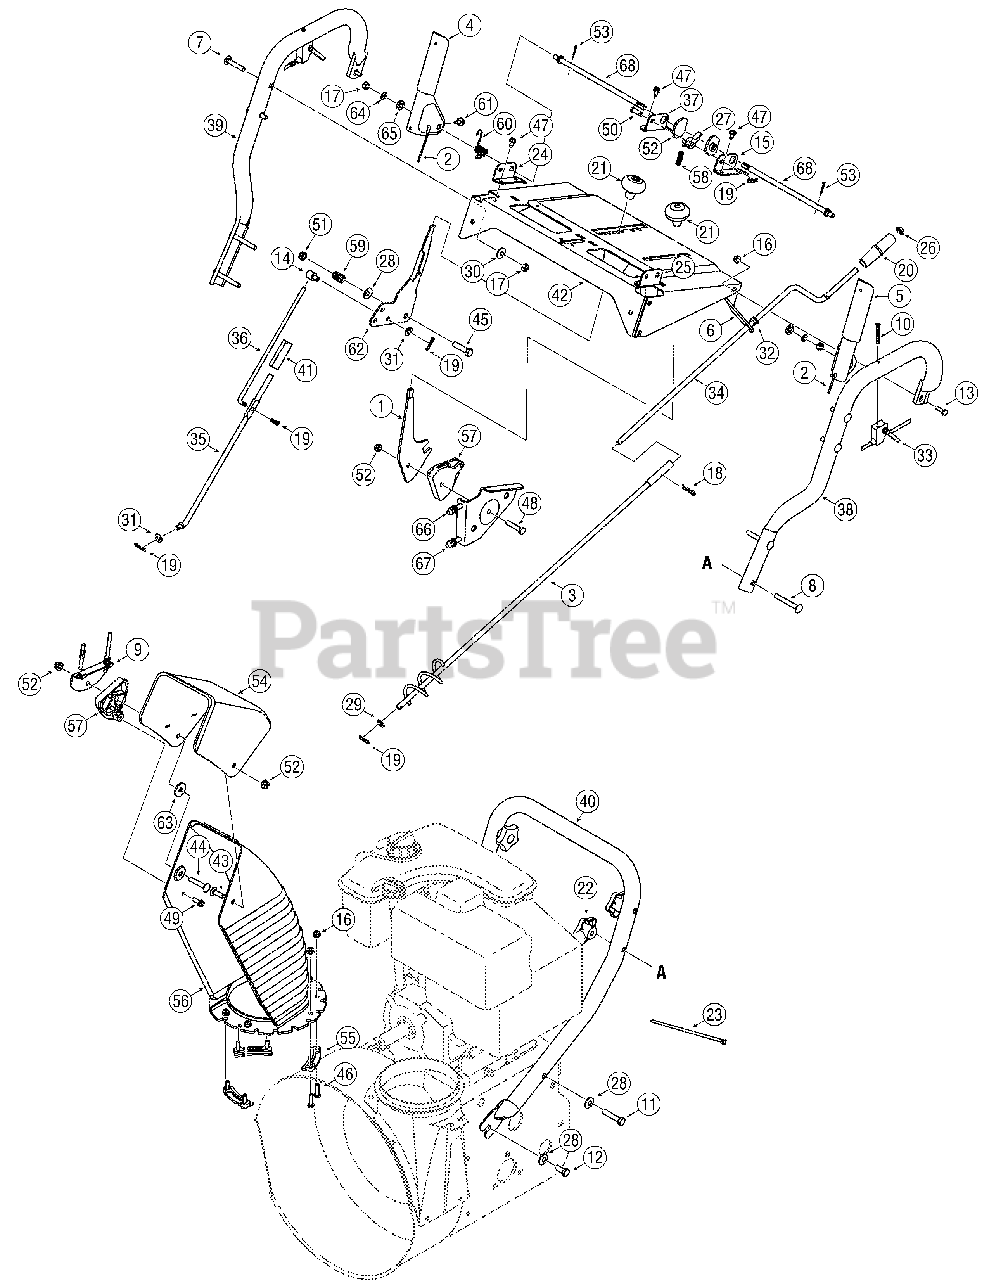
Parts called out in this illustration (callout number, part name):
1	Chute Tilt Handle
2	Cable Ass’y (Auger/Drive)
3	Lower Chute Crank Assembly
4	Engage Handle RH Black
5	EngagementHandle LHBlack
6	Upper Chute Crank Support
7	Carriage Bolt 5/16-18 x 1.75" Lg.
8	Carriage Bolt 5/16-18 X 2.50
10	Screw, #10-24 x 1.75
11	Hex Screw 3/8-16 x 1.75
12	Hex Screw 3/8-16 x .88
13	Hex Cap Bolt 1/4-20 x .75" Lg.
14	AdjustmentFerrule
15	LH Handle Support Brkt. 5/8"
16	Hex L-Flanged Nut 1/4-20 Gr. F Nylon
17	Hex Nut 5/16-18 hd. (Gr. 5)
18	Internal Cotter Pin
19	Int. Cotter Pin .072 x 1.13" Lg.
20	Knob 1.0 x 3.2
21	Shift Knob
22	Star Knob
23	Cable Tie
24	RH Handle Support Brkt. 3/8"
26	Push Nut 3/8" Rod
27	Cam Lock Pawl
28	Cupped Washer .375 ID x .870 OD x .063
29	Flat Washer .406" I.D. x .75" O.D.
30	Cupped Washer .345 ID x .88 OD x .060
31	Flat Washer .34 ID x .688 OD x .065
32	Plastic Bushing .380 ID
33	SteeringTrigger
34	Upper Chute Crank Assembly
35	Lower Shift Rod
36	Upper Shift Rod
37	RH Handle Support Brkt. 5/8"
41	Connector - Shift Rod
43	Carriage Bolt 5/16-18 x 1.00" Lg
44	Carriage Bolt 5/16-18 x 1.75" Lg.
45	Hex Scr 3/8-24 x 1.50
46	Hex Screw 1/4-20 x 1.00
47	Hex Wash S-Tapp Scr 1/4-20 x .50
48	Hex Bolt 5/16-18 x 1,50" Lg. Gr. 5
49	Hex Tapp Scr 1/4 x .75" Lg.
50	Clevis Pin .31 Dia. x 1.0" Lg.
51	Hex Nut 3/8-24
52	Cam Handle Lock
53	Cotter Pin 3/32 x .75
54	Upper Chute
55	Chute Flange Keeper
56	Lower Chute
57	Cable Guide
58	Compression Spring .62 OD x 6.12" Lg.
59	Compression Spring .38 ID x .88 Lg
60	Torsion Spring
61	Rub ber Bumper
62	Shift Lever
63	Flat Washer .344 ID X 1.125 OD X .125
64	L-Wash 5/16 ID
65	Washer (special)
66	Chute Control Cable 66"
67	Chute Control Cable w/clip
68	Cam Rod
